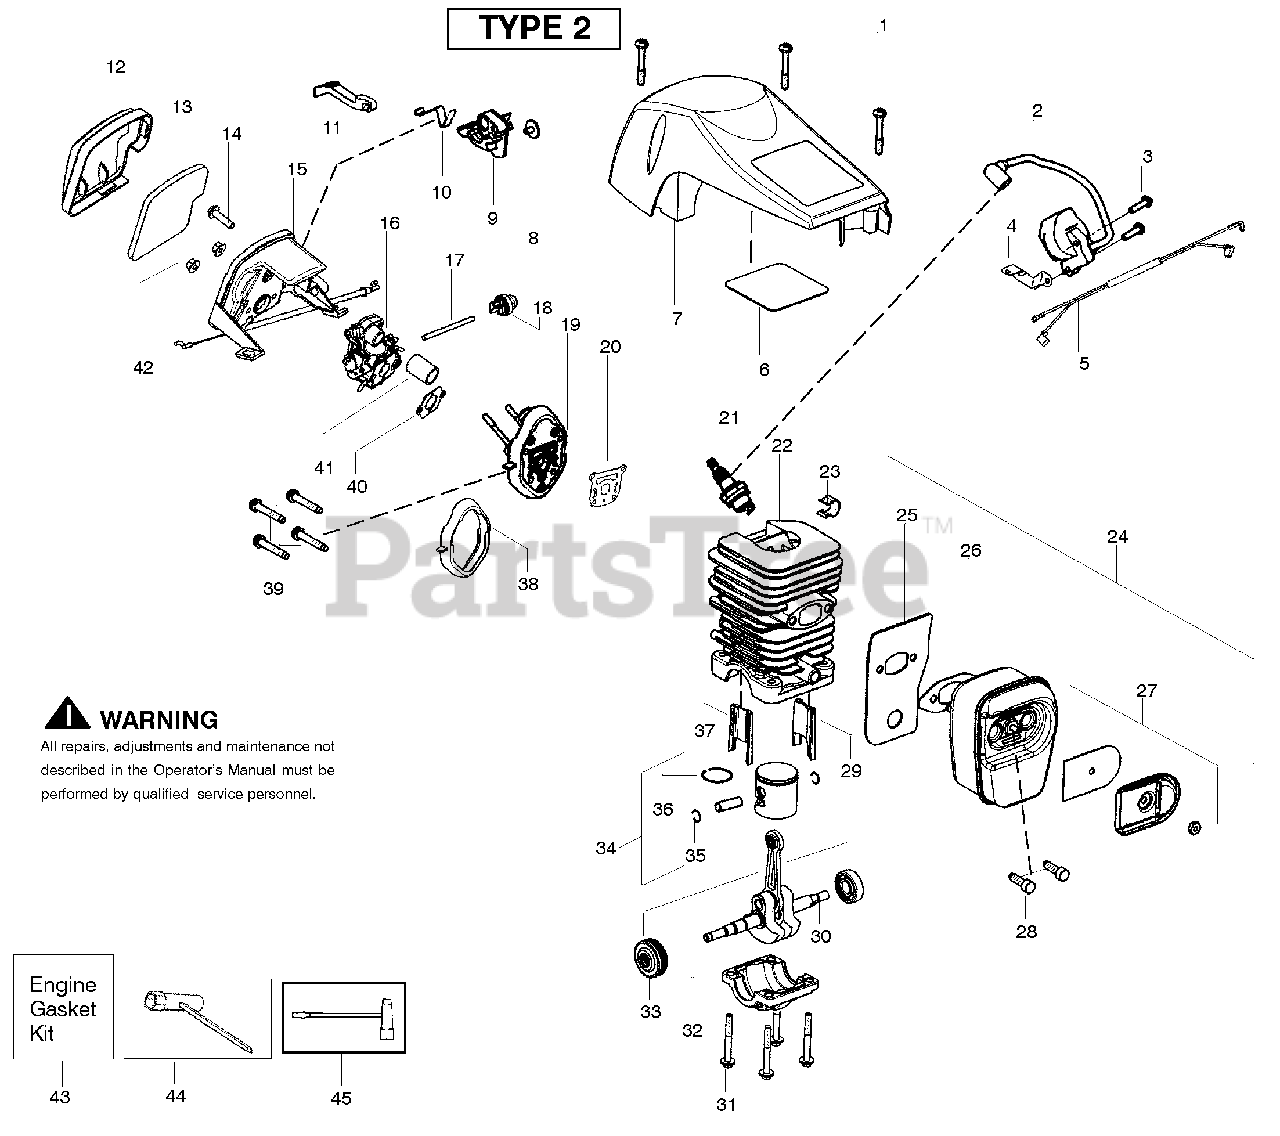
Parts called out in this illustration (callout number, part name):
2	Module-Ignition
4	Strap-Ground
5	Assy-Wire Harness
6	Reflector-Tape
7	Shield-Cylinder
9	Lever-Ignition Switch
10	Spring-Ignition Switch
11	Knob-Choke
12	Cover-Air Filter
13	Filter-Air
15	Housing-Air Filter w/cable
16	Carburetor Zama W26
17	Kit-Fuel Line (Small)
18	Bulb-Purge "snap-in"
19	Kit-Carb. Adaptor
20	Gasket-cyl. o-ring (kit)
21	Accy-Spark Plug (RCJ-7Y)
22	Kit-Cylinder
23	Clip-High Tension Lead
24	Kit-Muffler
25	Backplate-Muffler
26	Gasket-Muffler (kit)
27	Kit-Spark Arrestor
28	Bolt-Muffler
29	Insert-Left (black) Cyl.
30	Assy-Crankshaft/Rod
32	Cap-Crankcase
33	Assy-Bearing/Seal
34	Kit-Piston
35	Retainer-Piston Pin
36	Ring-Piston
37	Insert-Right (gray)Cyl.
38	Seal-Adaptor (kit)
40	Gasket-Carb. (kit)
41	Tube-Intake
42	Nut-Carb.
43	Kit-Gasket
44	Wrench-Bar
45	Scrench
